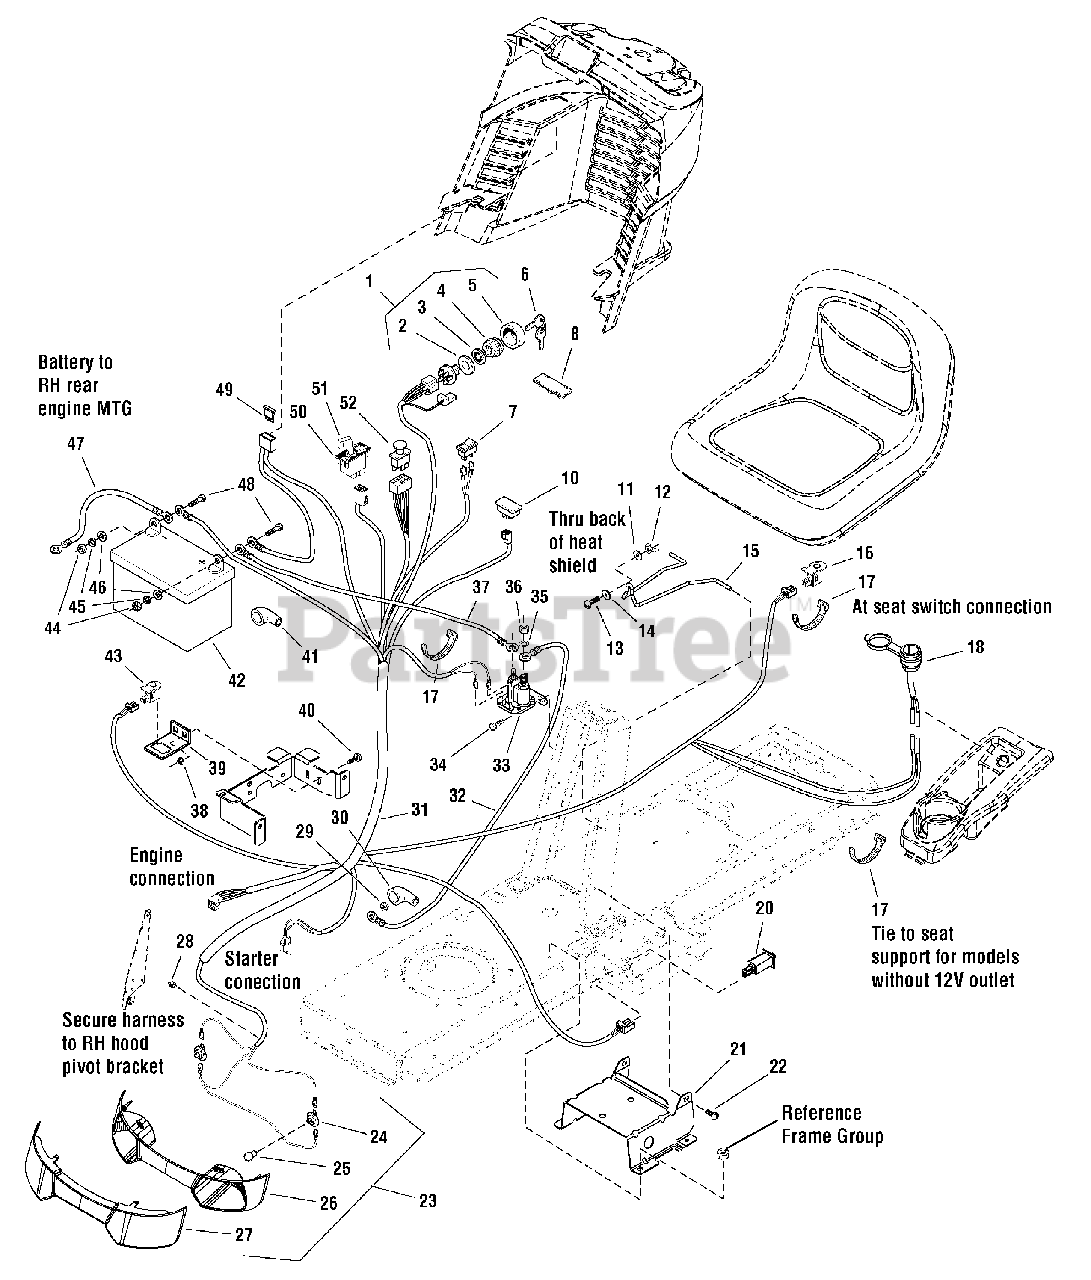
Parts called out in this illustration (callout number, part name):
1	SWITCH ASSEMBLY, Ignition, 6-Pole (Includes Ref. 2, 3, 4 & 5)
2	WASHER, 5/8
3	LOCKWASHER, Internal Tooth, 5/8
4	NUT, Hex, Flange, 5/8-32
5	COVER, Ignition
6	IGNITION KEY (Set of 2)
7	SWITCH, Headlights, 2 Terminal
8	PLUG, Hole, Square
10	METER, Hour, LCD
11	WASHER, Plain, 1/4 (6 Total for Export)
12	NUT, Wing, 1/4-20
13	CARRIAGE BOLT, 1/4-20 x 7/8
14	NUT, Push On
15	HOLD DOWN, Battery
16	SWITCH, Push Button (NC)
17	TIE, Self Locking 7-5/16
18	OUTLET, 12 Volt DC Power
20	SWITCH, Push Button (NO/NC)
21	SUPPORT, Battery 12 GA
22	SCREW, Taptite, 5/16-18 x 5/8
23	HEADLIGHT ASSEMBLY (Includes Ref. 24, 25, 26 & 27)
24	SOCKET ASSEMBLY
25	BULB, 1141-12V 21CP
26	REFLECTOR, Headlight
27	LENS, Headlight
28	CLIP, Speed Wire
29	NUT, Hex, Flange, 1/4-20
30	COVER, Terminal
31	HARNESS, Wiring
32	CABLE, Solenoid to Starter
33	SOLENOID
34	SCREW, Taptite, 1/4-20 x 1/2
35	LOCKWASHER, External Tooth, 5/16
36	NUT, Hex, 5/16-24 NF
37	CABLE, #6 x 10 Long, with 2 Ring Terminals, Battery to Solenoid
38	NUT, Hex, Flange Whizlock, 5/16-18
39	SUPPORT, RMO Switch
40	CARRIAGE BOLT, 5/16-18 x 3/4
41	BOOT, Insulator
43	SWITCH, Push Button (NO), Reverse Pedal
44	NUT, Hex, Full, 1/4-20
45	LOCKWASHER, 1/4
46	WASHER, 1/4 I.D.
47	CABLE, Battery to Ground
48	CAPSCREW, Hex Head, 1/4-20 x 3/4
49	FUSE, Wiring Harness
50	SWITCH, RMO Module Only
51	KEY, RMO Module, Plastic
52	SWITCH, PTO, Push/Pull
